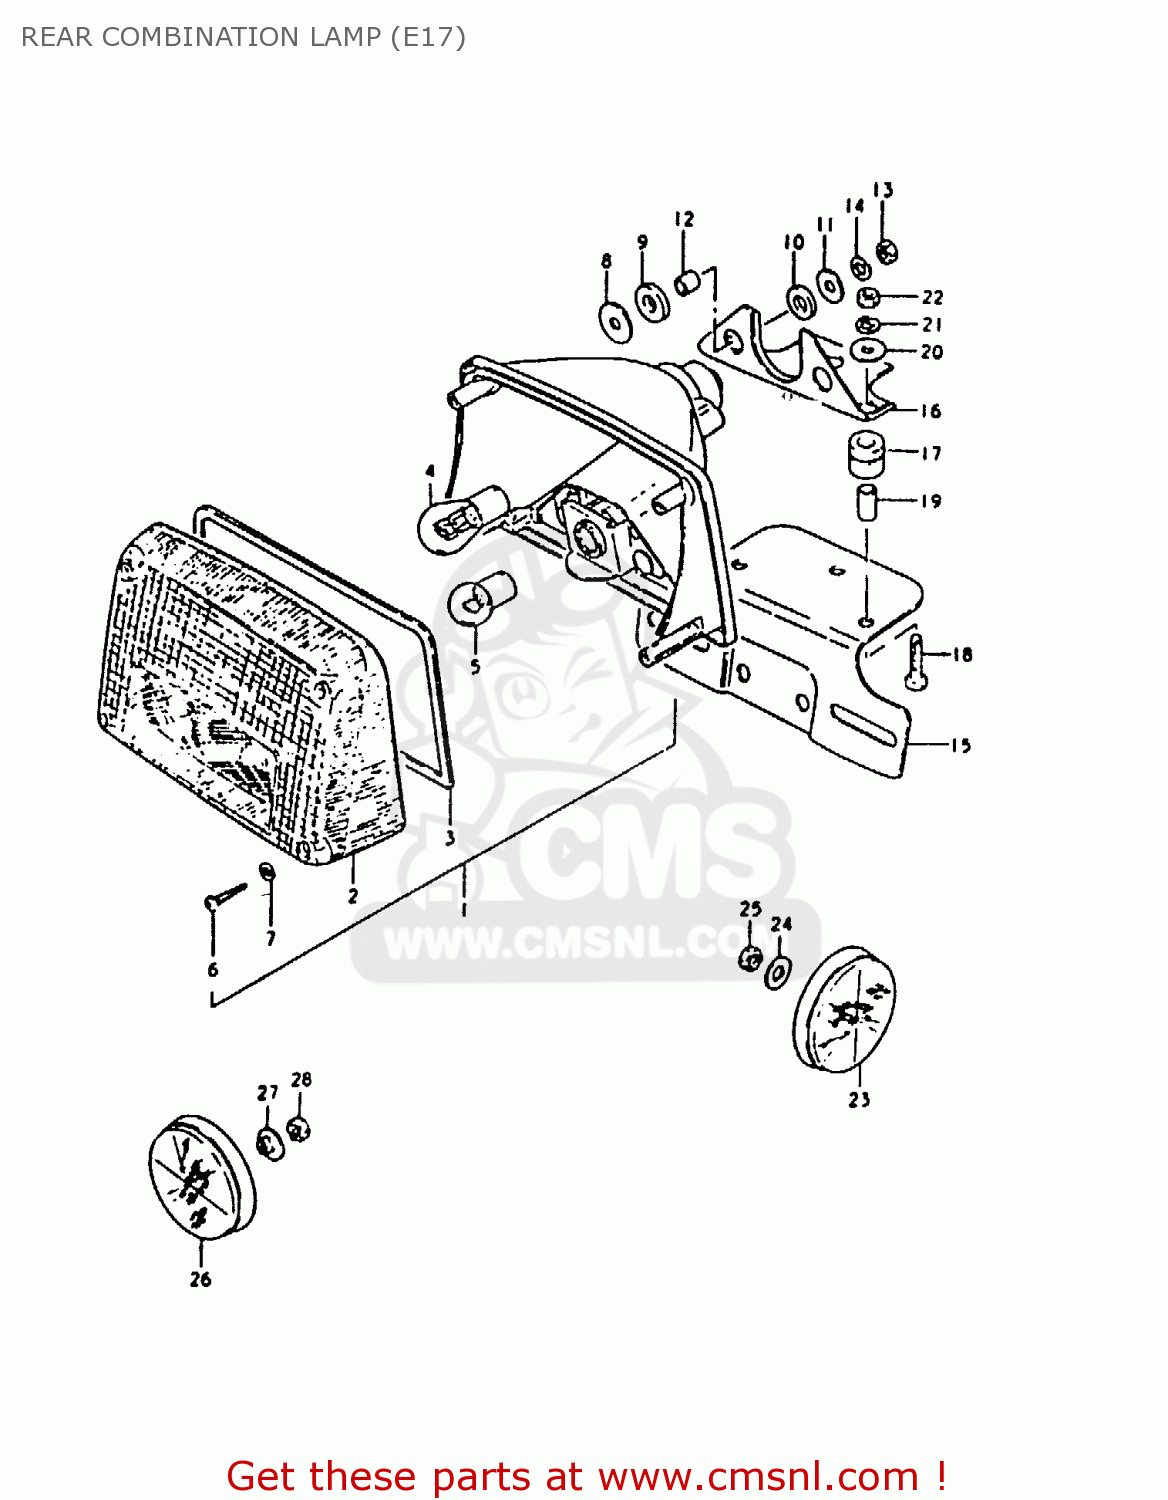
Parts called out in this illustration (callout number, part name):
1	LAMP, REAR COMBINATION
2	LENS
3	GASKET (NAS)
4	BULB 12V21/5W
5	BULB
6	SCREW
7	GASKET (NAS)
8	WASHER
9	CUSHION
10	CUSHION
11	WASHER(6,5X22X1.6)
12	SPACER(6.1X9X7.5)
13	NUT
14	LOCK WASHER
15	BRACKET, LICENCE PLATE
16	BRACKET,LICENSE PLATE
17	CUSHION, BRACKET
18	BOLT
19	SPACER (6.4X9X15.5)
20	WASHER
21	LOCK WASHER
22	NUT
23	REFLEX REFLECTOR,RR
24	WASHER
25	NUT
26	REFLECTOR,REFLEX
27	SPACER
28	NUT
